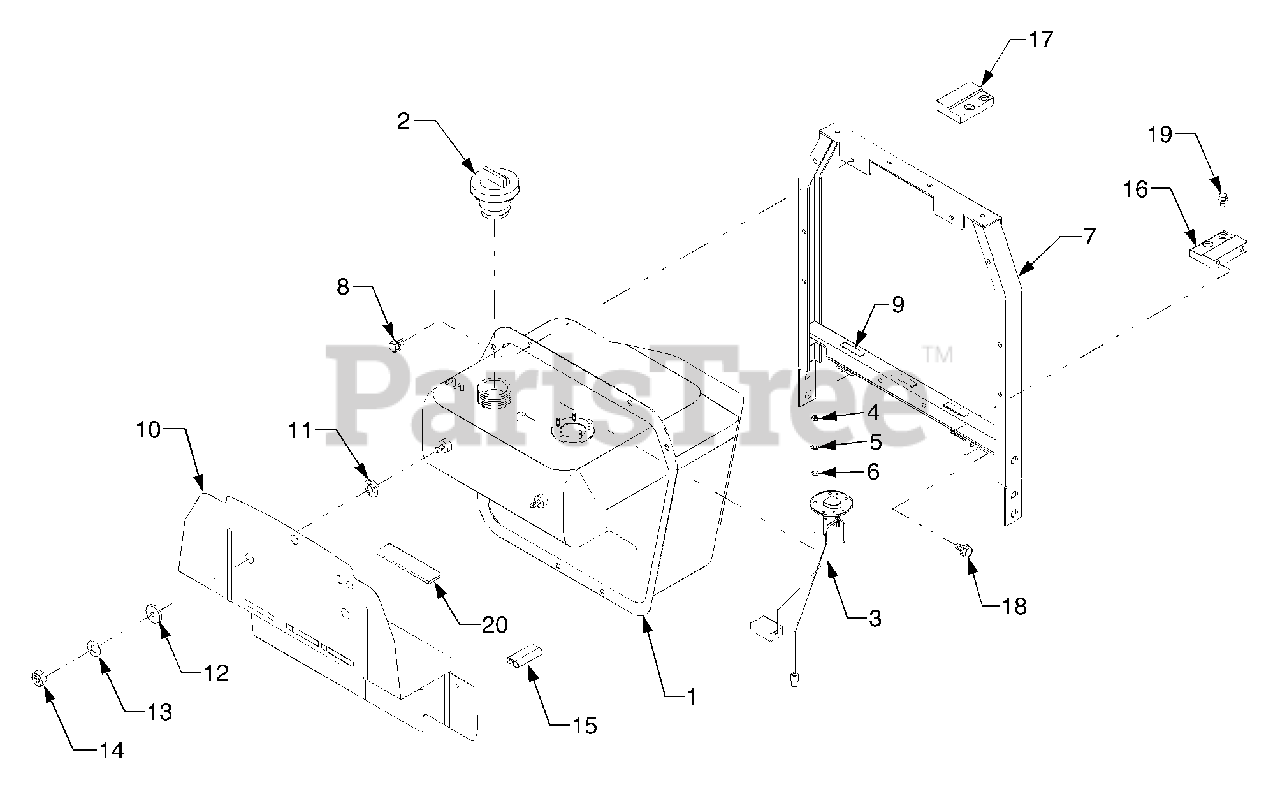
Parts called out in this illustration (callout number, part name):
2	Fuel Cap Assy
3	Fuel Sensor Ass'y
5	Washer, Spring
6	Washer, Plain
7	Bracket, Bonnet
9	Rubber, Cushion
10	Plate, Shuttle
13	Washer, Plain
20	Rubber, Cushion
